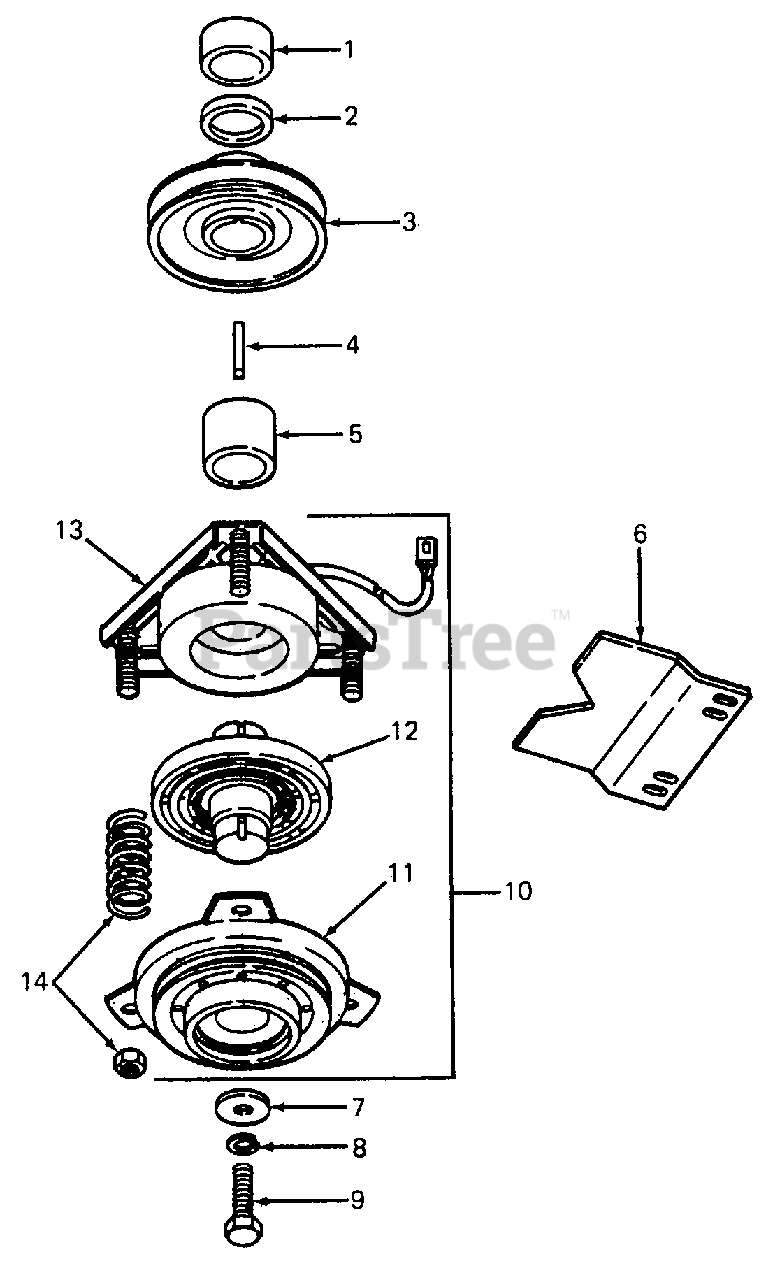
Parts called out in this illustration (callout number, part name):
1	Spacer, Engine Pulley
2	Spacer, 1.0 X 1.32 X .40
3	Pulley, Engine (A sec. X 3.5 OD)
4	Key, 1/4 X .75 Sq.
5	Bushing, 1.2 X 1.5 X .620
7	Washer, .445 X 1.5 X .172
8	Washer, Lock 7/16
9	Bolt, 7/16-20 X 3.25 GR 5
10	Clutch Assy, PTO
11	Armature
13	Field
14	Mounting Accessories Hex Nuts Springs
